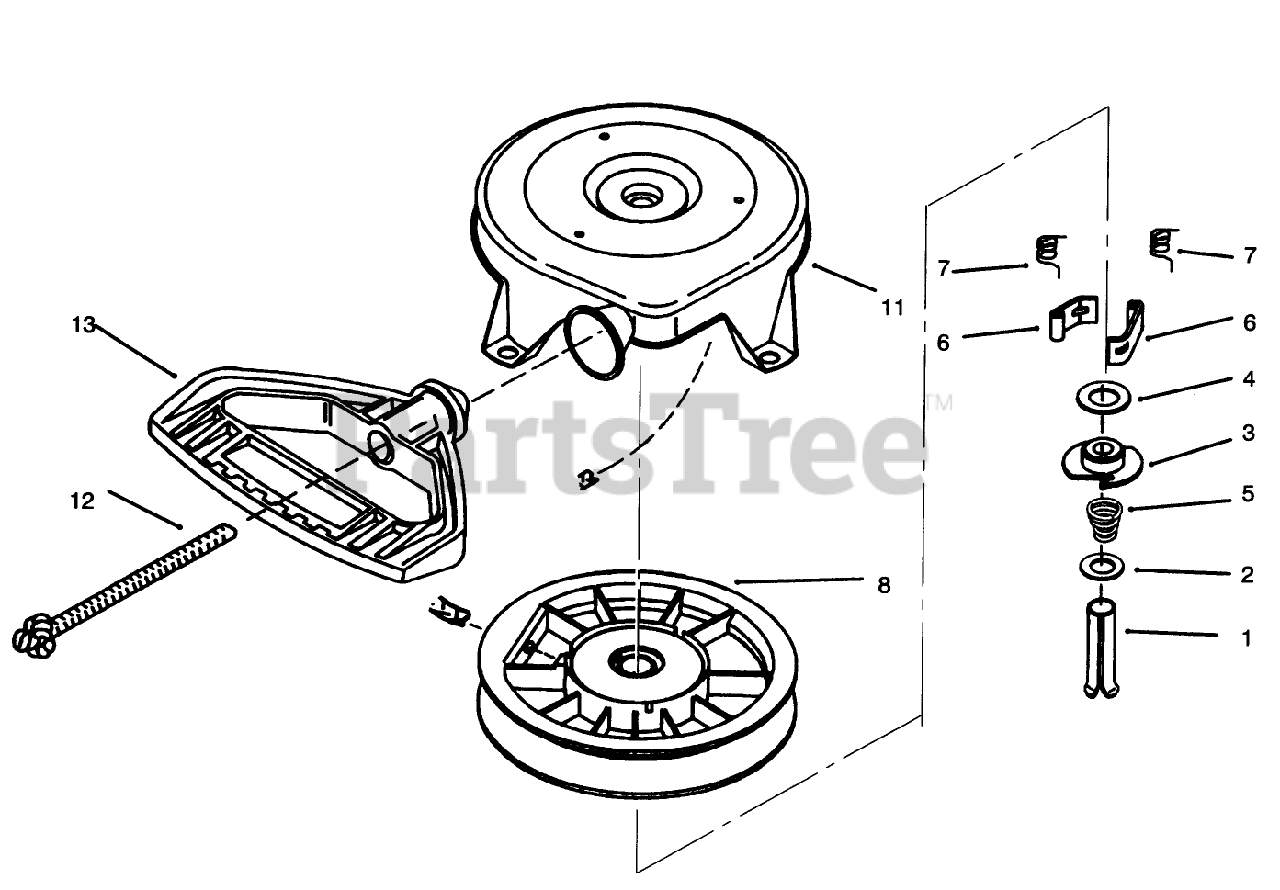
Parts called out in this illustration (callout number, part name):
1	Pin, Spring (Incl. Ref. #7)
2	Washer
3	Retainer
4	Washer
5	Spring-Brake
6	Dog-Starter
7	Spring-Dog
8	Pulley and Rewind Spring ASM
11	Housing Assy.-Starter
12	Rope-Starter
13	Handle-Starter, Mitten Grip
